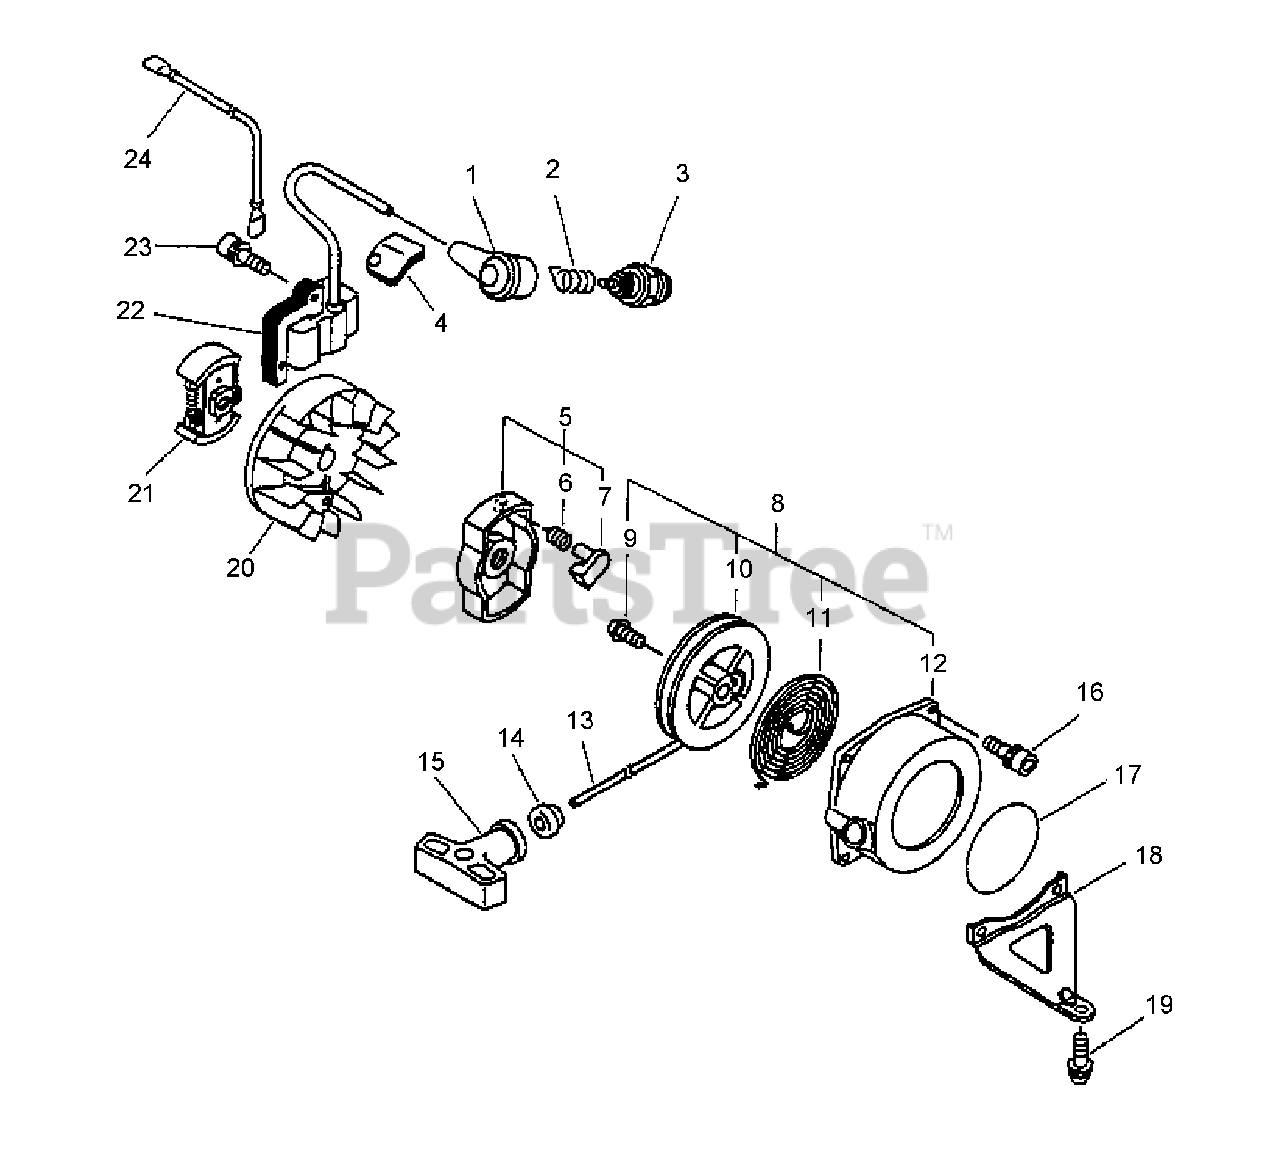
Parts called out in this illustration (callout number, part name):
1	CAP, SPARK PLUG
2	TERMINAL, SPARK PLUG
3	SPARK PLUG - BPM-7Y
5	PAWL ASSY, STARTER
6	SPRING, RETURN
7	PAWL, STARTER - BLACK
8	STARTER ASSY, RECOIL
9	SCREW
10	REEL, ROPE
12	GUIDE, ROPE
13	GRIP, STARTER
14	SPRING, RECOIL
15	CASE, RECOIL STARTER
16	BOLT 4×16
17	LABEL, ECHO
18	SUPPORT, HANDLE
19	SCREW 5×16
21	CLUTCH ASSY
22	COIL, IGNITION
23	SCREW 4×22
24	LEAD
